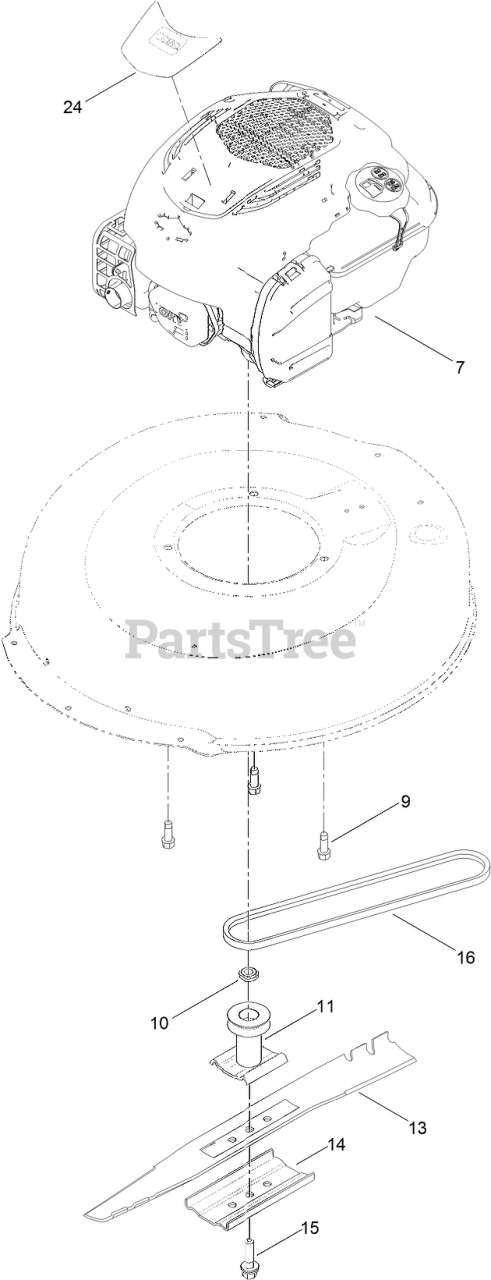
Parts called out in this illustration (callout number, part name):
9	SCREW-TAPTITE
10	Spacer-Driver
11	DRIVER-BLADE
13	BLADE-21 INCH
14	SUPPORT-BLADE
15	BOLT-BLADE
16	V-BELT
24	DECAL-SHROUD
